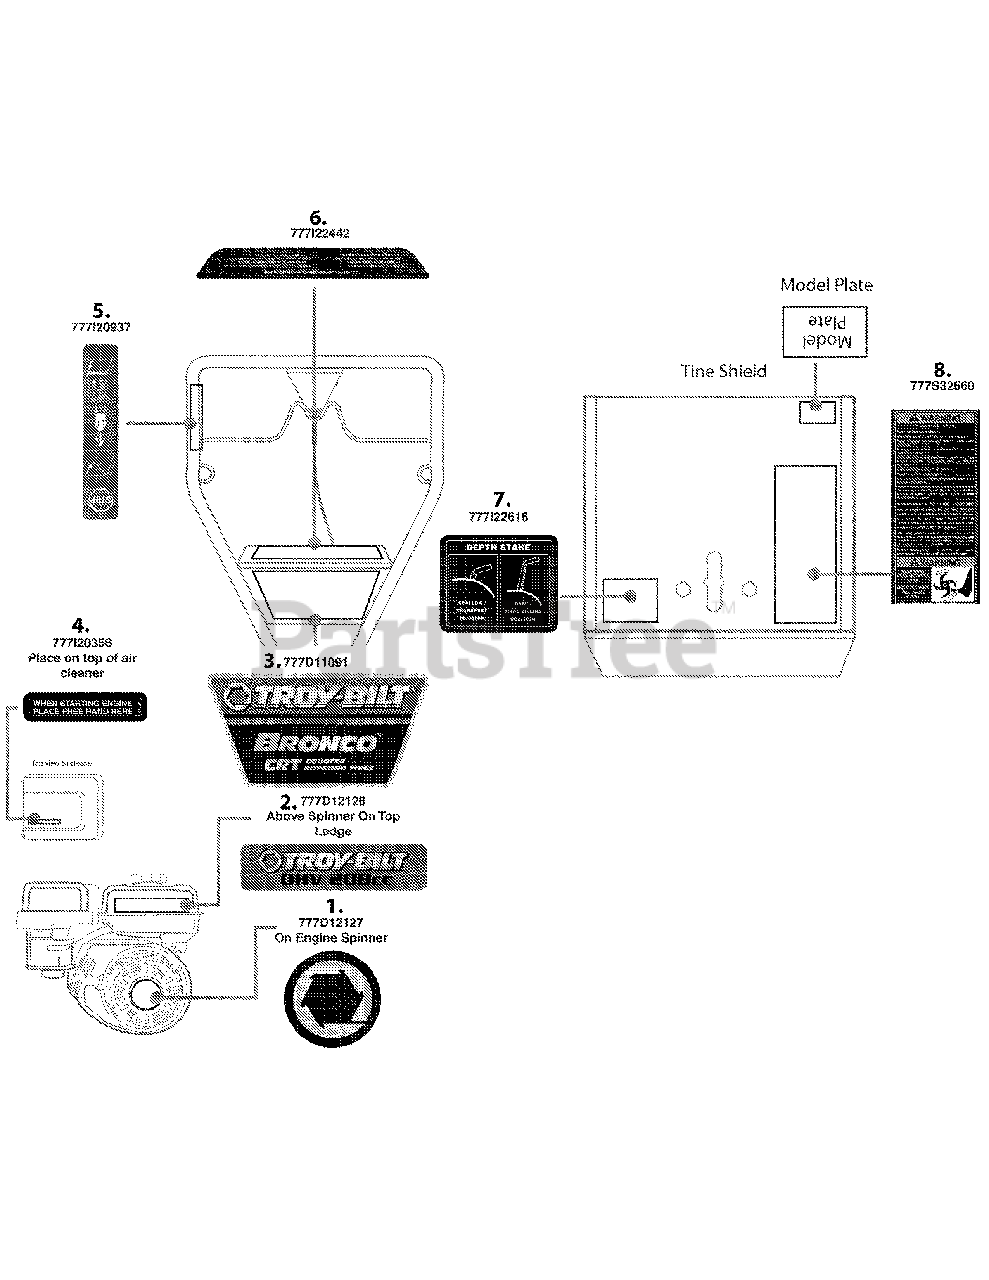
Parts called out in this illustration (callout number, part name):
1	LABEL-TILLER MTD ENGINE
2	LABEL-TILLER MTD ENGINE TROY
3	LABEL-TILLER HANDLE BRONCO CRT
4	LABEL-PLACE HAND HERE
5	LABEL-BAIL CONTROL
6	LABEL-HANDLE PANLECRT
7	LABEL:TILLER TINE SHIELD DEPTH
8	LABEL:TILLER TINE SHIELD
